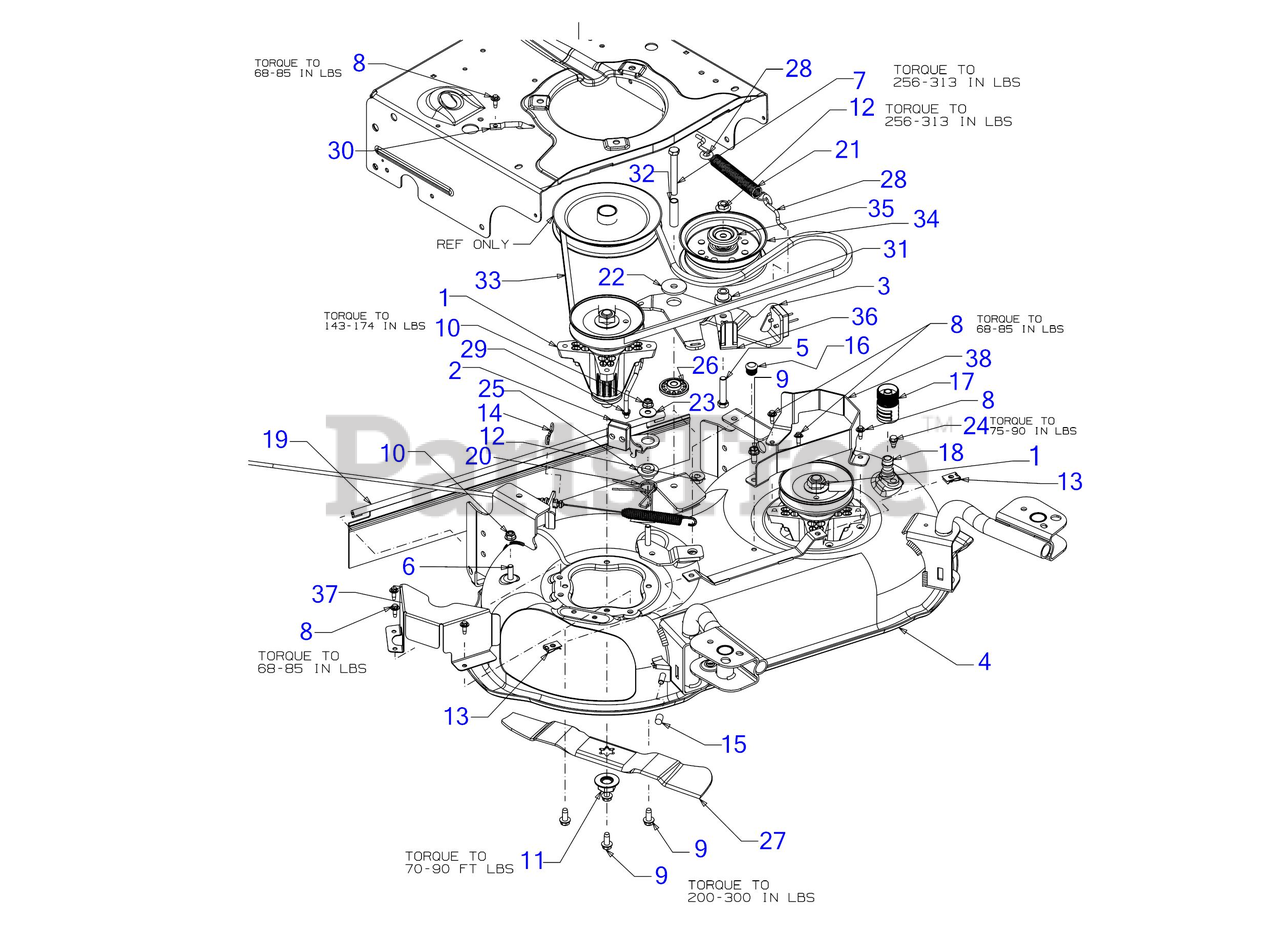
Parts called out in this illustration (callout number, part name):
1	SPINDLE ASM 4.6" DIA
2	DECK BRAKE ASSEMBLY
3	IDLER PIVOT ASSEMBLY BRACKET
5	HEX SCREW 3/8-16 x 1.75 GR5
6	SCREW 5/16-18 x 1.0 GR5
7	SCREW 3/8-16 x 3 GR8
8	SCREW M6-1 x .625
9	SCREW 5/16-18 x .750
10	FLANGE LOCK NUT 5/16-18
12	FLANGE LOCK NUT
14	PIN:COTTER
16	ROUND PLUG
17	WATER NOZZLE
18	DECK WASH NOZZLE
19	23.25" TRAIL SHIELD
20	TORSION SPRING
21	EXTENSION SPRING 5.80 X .75
22	FLAT WASHER .390x1.500x.134
23	FLAT WASHER 344X1.00
24	SHOULDER SCREW 1/4-20 x .50
25	SHOULDER SPACER .750 x .145
26	SHOULDER SPACER
27	14.20" BLADE (MULCH)
29	DECK BRAKE ROD
30	ENGINE PULLEY BELT KEEPER ROD
31	SHOULDER SPACER
33	DECK BELT
34	IDLER PULLEY 4.50" DIA
35	IDLER PULLEY CAP
